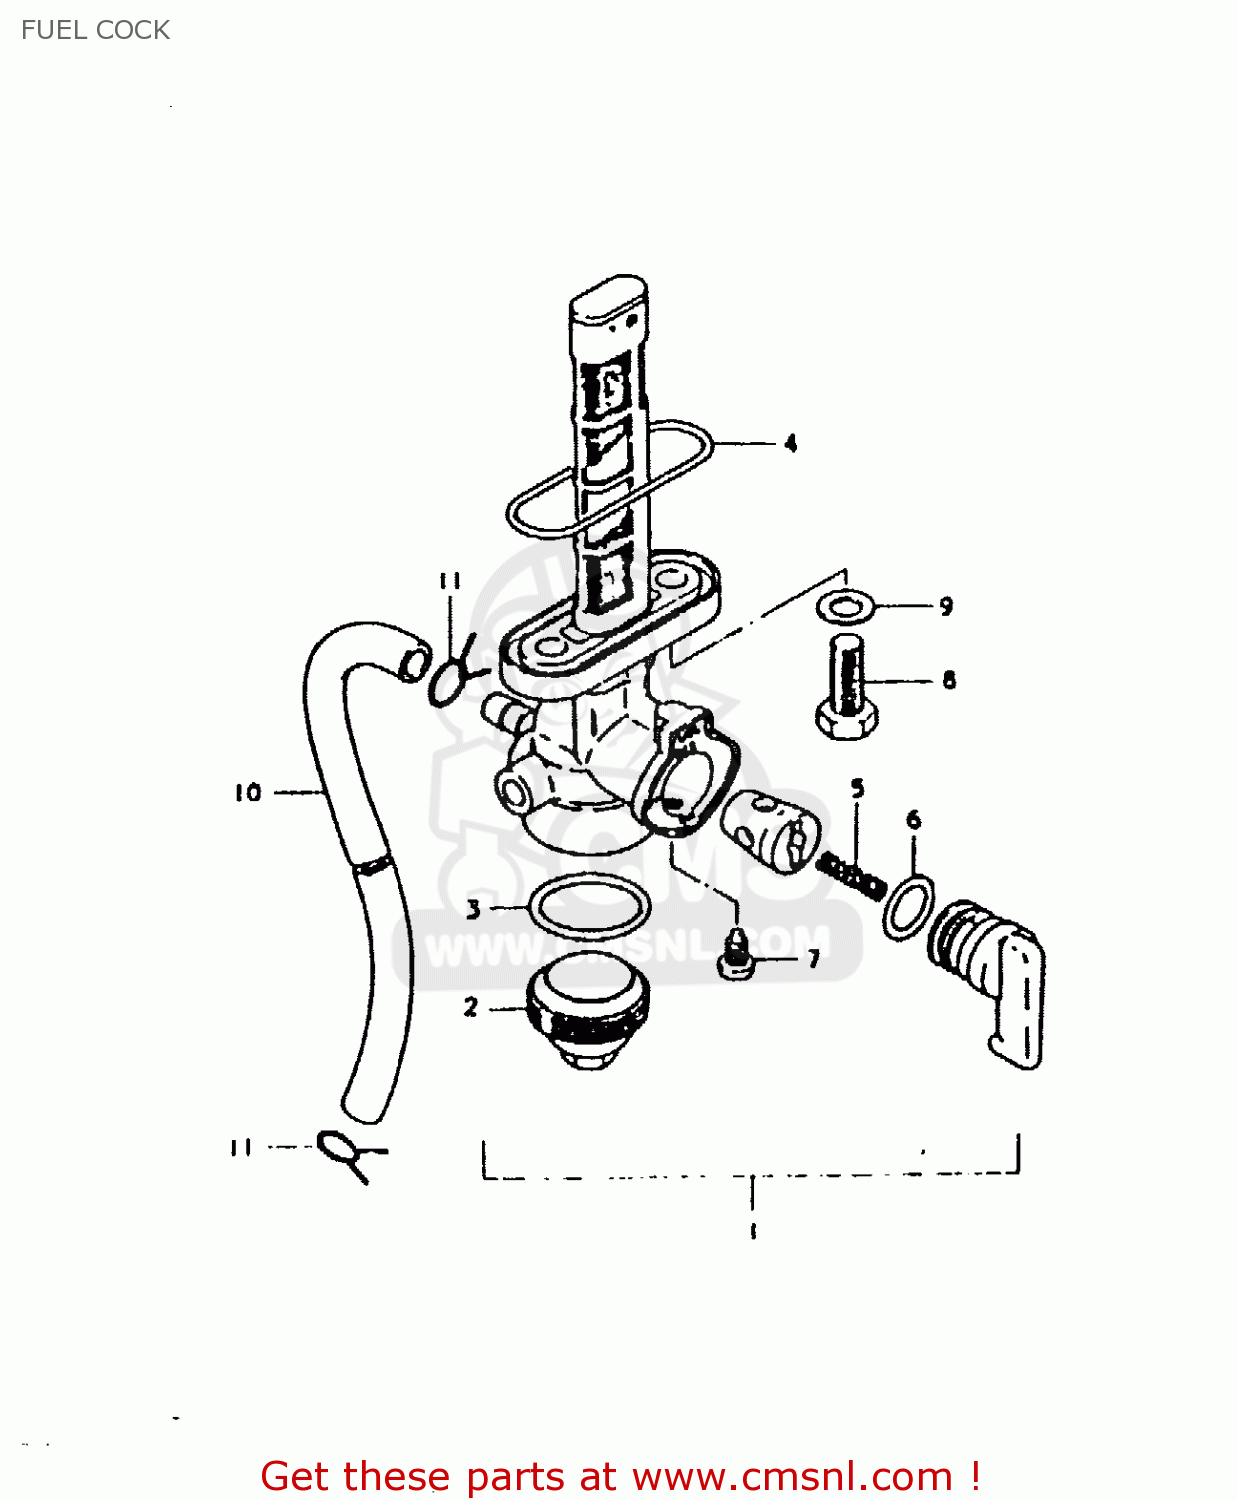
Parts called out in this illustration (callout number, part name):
1	COCK ASSEMBLY,FUEL
2	CUP,STRAINER
3	GASKET,FILTER (NAS)
4	O RING,FUEL COCK
5	SPRING
6	O-RING
7	SCREW
8	BOLT L:16
9	GASKET
10	HOSE
11	CLIP
